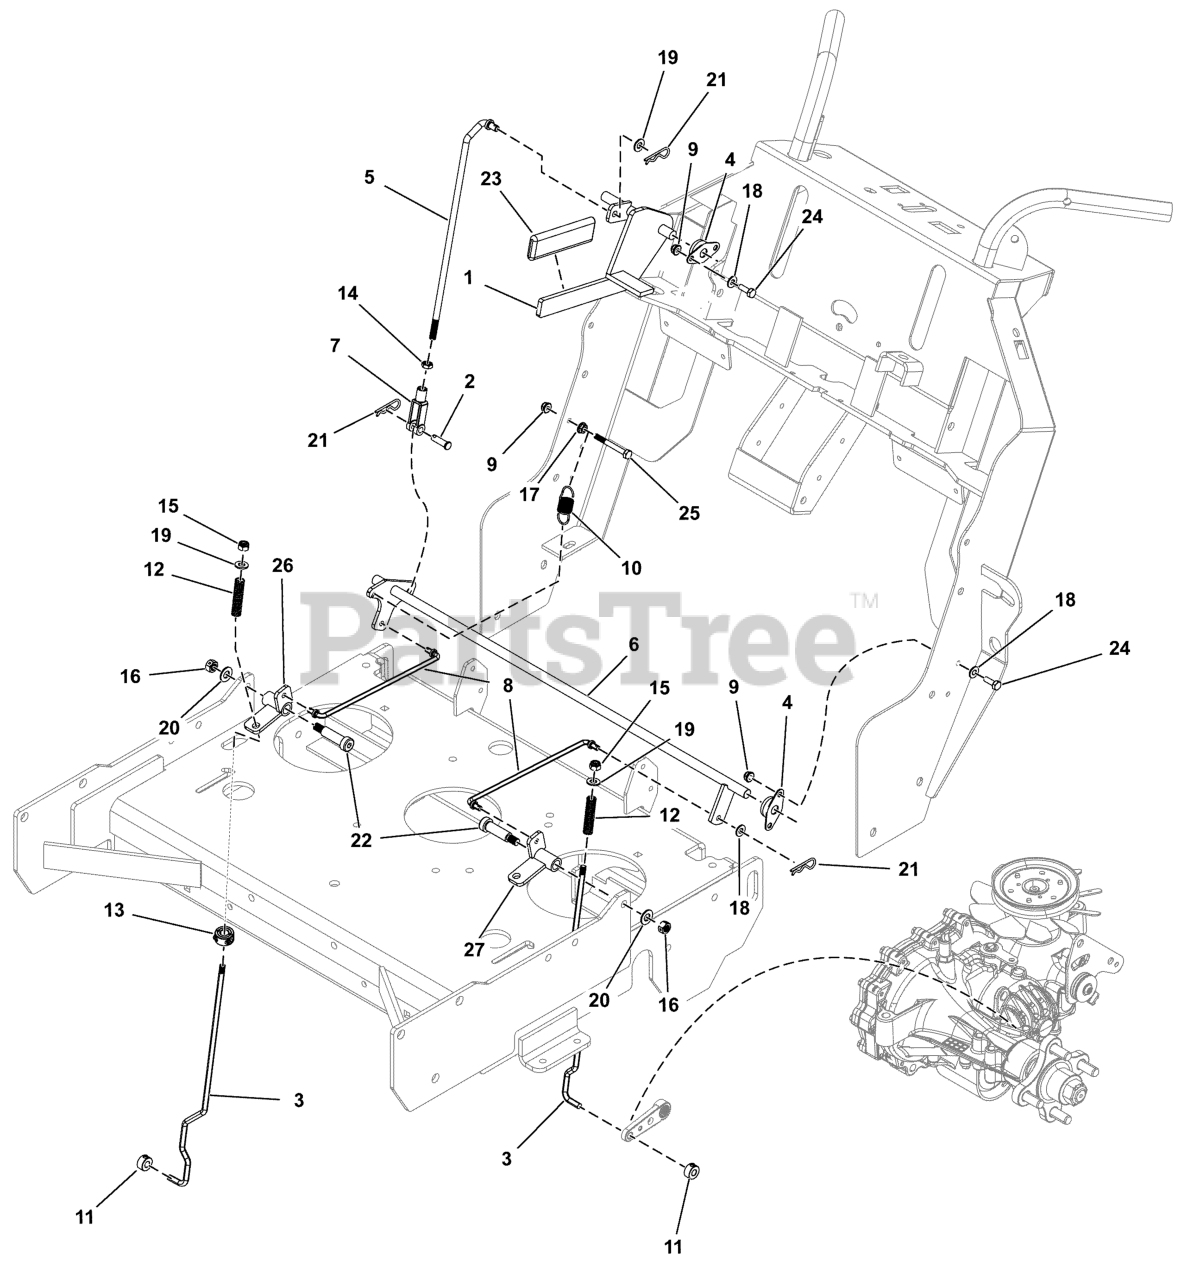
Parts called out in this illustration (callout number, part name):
1	WELD, BRAKE HANDLE, W45 - BLK
2	PIN, CLEVIS, 5/16 X 1, PLATED
3	ROD, PARKING BRAKE, W45
4	BEARING, 1/2 FLANGED, PLASTIC BALL
5	ROD, PARKING BRAKE, W35, UPPER
6	WELD, BRAKE ROD, W35 - BLK
7	CLEVIS, 5/16-24, STEEL, CLEAR ZINC
8	ROD, PARKING BRAKE, W35, UPPER
9	NUT, 1/4-20 Hex Nylock Flange
10	SPRING-EXT, .740 ODX2.025LGX.072WR, BLK
11	COLLAR, 5/16" Set
12	SPRING-COMP, .375IDX2.75LGX.054WR, SS
13	COLLAR, DOUBLE SPLIT, 7MM
14	NUT, Hex Jam, 5/16-24
15	NUT, 5/16-24 HEX NYLON LOCK
16	NUT, Hex, Side Lock, 3/8-16
17	NUT, 1/4-20 HEX SERR. FLANGE
18	WASHER, 1/4 SAE
19	WASHER, 5/16" SAE
20	WASHER, 3/8 SAE
21	PIN, HAIR, .0585 X 1-1/8, 1/4 EYE, YZ
22	BOLT, 3/8-16 x 1-1/2", 1/2" SHOULDER
23	GRIP, FOAM, 1/4 X 1 X 4.1
24	BOLT, 1/4"-20 X 3/4" GD5 YZ
25	BOLT, 1/4-20 X 2-1/4 GD5 CZ
26	WELD, BRAKE PIVOT, W35 - RH - BLK
